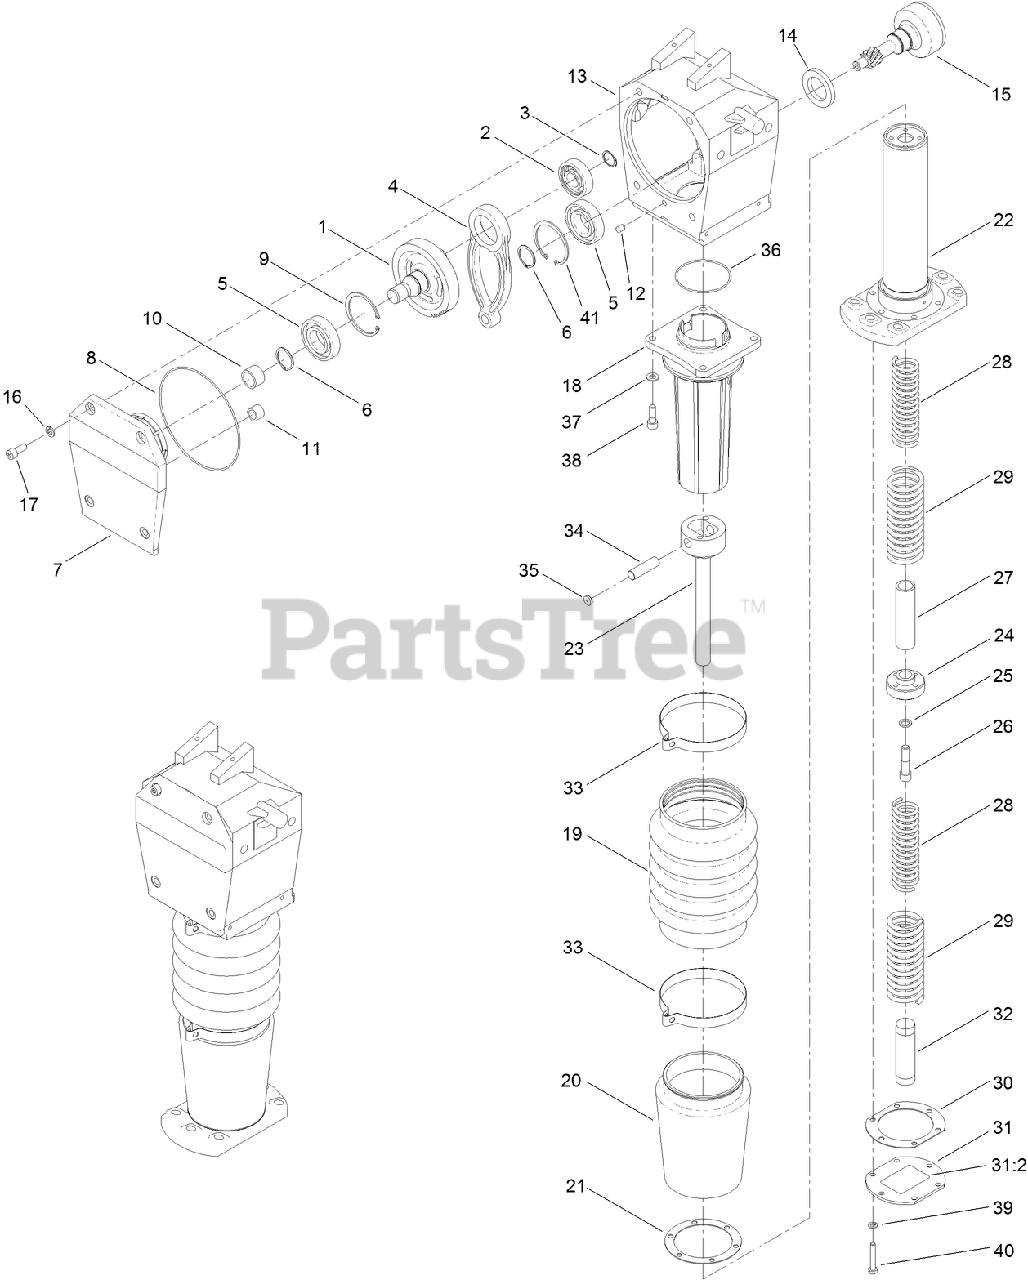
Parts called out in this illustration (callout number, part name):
1	GEAR-HELICAL
2	BEARING-BALL
3	RING-EXTERNAL
4	ROD-CONNECTING
5	BEARING-BALL
6	RING-SNAP, EXTERNAL
7	COVER-FRONT
8	O-RING
9	RING-INTERNAL
10	BEARING-NEEDLE
11	BEARING-NEEDLE
13	GEARCASE
14	SEAL-SHAFT
15	PINION
17	SCREW-HSH
18	GUIDE-TUBE
19	BOOT-STOMPER
20	COVER-HOUSING, SPRING
21	GASKET-HOUSING, SPRING COVER
22	HOUSING-SPRING
23	ROD-PISTON
24	PUCK-PISTON
25	WASHER-LOCK
26	SCREW-HSH
27	SNUBBER-SPRING, UPPER
28	SPRING-COMPRESSION, INNER
29	SPRING-COMPRESSION, OUTER
30	GASKET-COVER, SPRING
31	BOTTOM SPRING COVER ASM
31:2	DECAL-WARNING, SPRING
32	SNUBBER-SPRING, LOWER
33	CLAMP-BOOT, STOMPER
35	BUTTON-PIN, CAPTIVATOR
36	O-RING
37	WASHER-FLAT
38	SCREW-HSH
39	WASHER-LOCK
40	SCREW-HH
41	RING-INTERNAL
